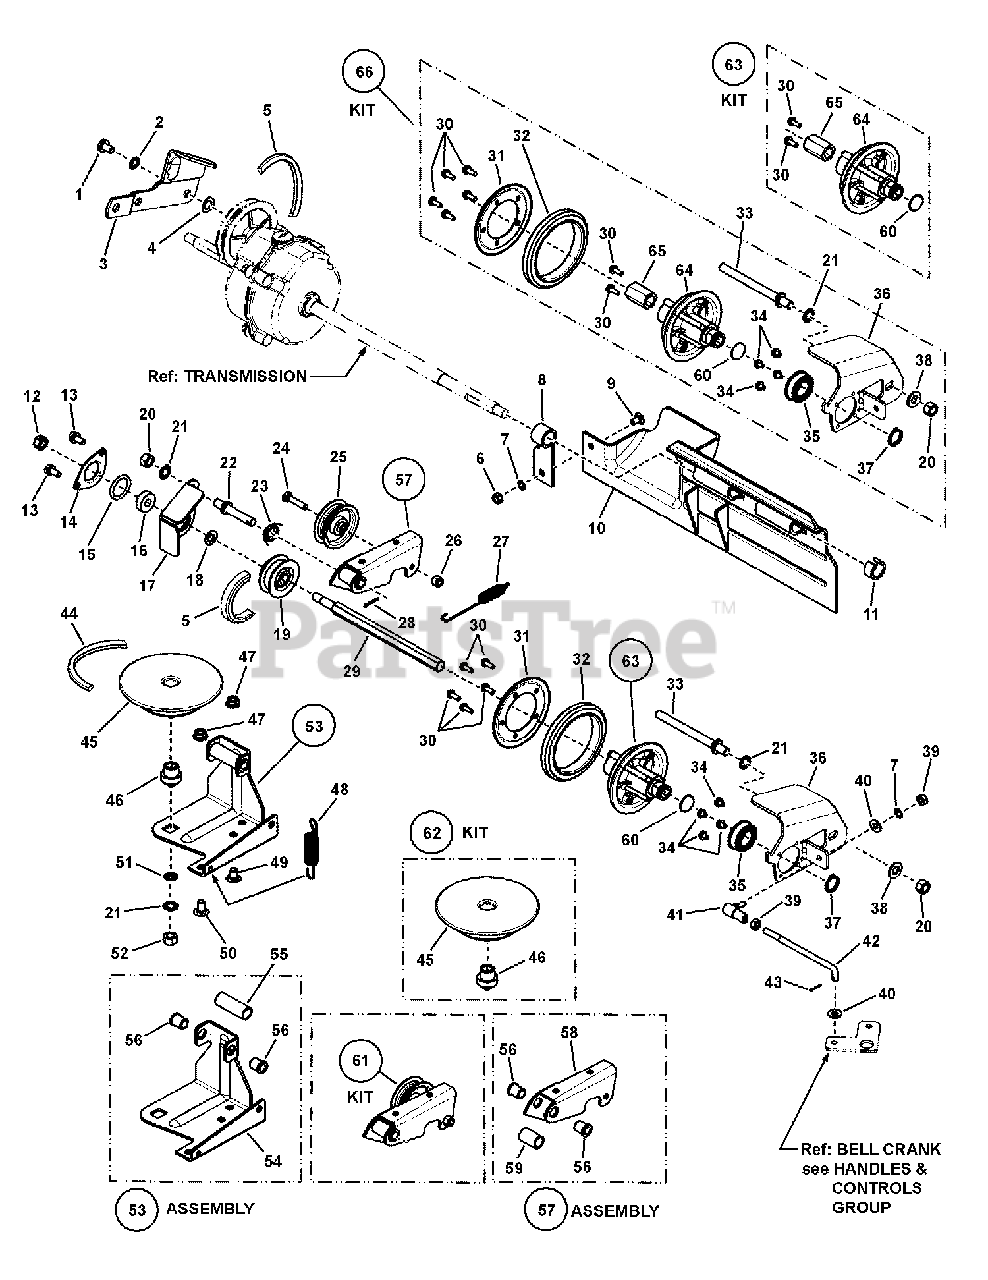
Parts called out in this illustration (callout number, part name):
1	SCREW, 5/16-18 x 1/2" Pan Head Self-Tap (Torx)
2	WASHER, 5/16" Internal Tooth Lock
3	LINK, Differential, Commercial
4	WASHER, Curved, .44 x .78 x .025 BZ
5	BELT, Poly-V, V21
6	NUT, 1/4-20 Hex, GR 5 or B, ZP
7	WASHER, 1/4" Internal Tooth Lock, YZ
8	SUPPORT, Guard
9	BOLT, 1/4-20 x 1/2" Short Square Neck Carriage, GR 5
10	FOOT GUARD, 21"
11	RING, Split, .68 x .93 x .44 (Black)
12	NUT, 3/8-24 Hex Center lock, GR 5, YZ
13	SCREW, 1/-20 x 1/2" Hex Flange Self-Tap
14	HOLDER, Bearing (Outer Half)
15	O-RING, V21
16	BALL BEARING, Spherical O.D., .38 I.D.
17	HOLDER, Bearing (Inner Half)
18	WASHER, .390 I. D. Flat
19	PULLEY, Poly-V, 2.00 O.D.
20	NUT, 3/8-24 Hex, GR 5, YZ
21	WASHER, 3/8" Internal Tooth Lock, BZ
22	STUD, Idler, (3/8-24 thread) YZ
23	SPRING, V21
24	SCREW, 1/4-28 x 1-3/8" Hex Head Cap, GR 5
25	PULLEY, Idler, V21
26	NUT, 1/4-28 Hex Top Lock, GR 5, BZ
27	SPRING, Clutch
28	COTTER PIN, 3/32 x 1/2"
29	HEX SHAFT (Heat Treated)
30	SCREW, #10-24 x 1/2" Hex Washer Self-Tap (Torx)
31	SIDE PLATE, Drive Tire
32	DRIVEN RING
33	GUIDE, Thrust Plate (3/8-24 thread)
34	SCREW, #10-32 x 1/4" Hex Washer self-Tap
35	BALL BEARING, 3/4" Bore, Commercial
36	THRUST PLATE, Short
37	RETAINING RING, .625 External
38	WASHER, 3/8" Flat
39	NUT, 1/4-28 Hex GR 5 or B, YZ
40	WASHER, .28 x .63 x .065, Flat, YZ
41	BALL JOINT
42	LINK, Transfer (1/4-28 thread)
43	COTTER PIN, .06 x .50, YZ
44	BELT, Engine Drive (Stretch)
45	DRIVE DISC, Steel
46	BUSHING
47	NUT, 5/16-18 Hex Flange Lock, GR 5
48	SPRING, Extension, .58 x 3.2
49	BOLT, 5/16-18 x 1/2" Short Square neck Carriage, GR 5
50	BOLT, 5/16-18 x 5/8" Round Head Short Square Neck, GR 5 BZ
51	RETAINER, 5/16" Bolt
52	NUT, 3/8-16 Hex, GR 5, YZ
53	ASSEMBLY, Deck Bracket, P21S
54	BRACKET, Deck, P21S
55	SPACER, .65 OD x .500 ID x 1.75 L
56	BUSHING, Flange
57	ASSEMBLY, Idler Arm (Bushing & Spacer)
58	ARM, Clutch Idler
59	SPACER, Idler Arm
60	WASHER, Shim, .75X1.0X.021
61	ASSEMBLY, Clutch Idler
62	ASSEMBLY, Drive Disc, Square, P21S
63	KIT, Hub & Bushing
64	HUB, Driven Disc
65	BUSHING, Drive, Hex
66	ASSEMBLY, Driven Disc, Short, Commercial, MY08
